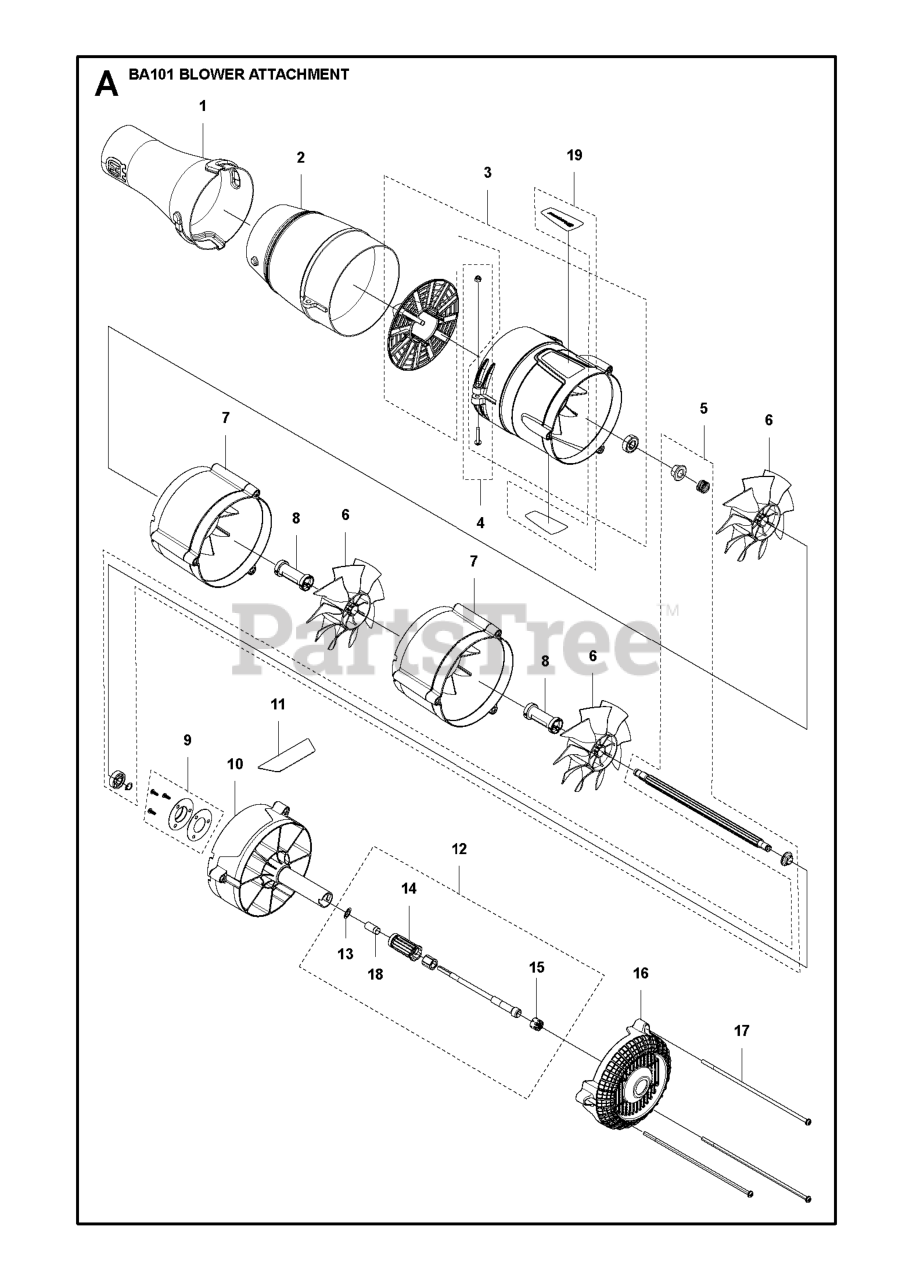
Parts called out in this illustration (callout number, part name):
3	KIT HOUSING HEAD
4	KIT BOLT NUT
7	HOUSING BODY
11	DECAL WARNING
12	KIT SHAFT CONNECTING
13	WASHER PUSH ON
14	PLUG TILLER/DETHATCHER
